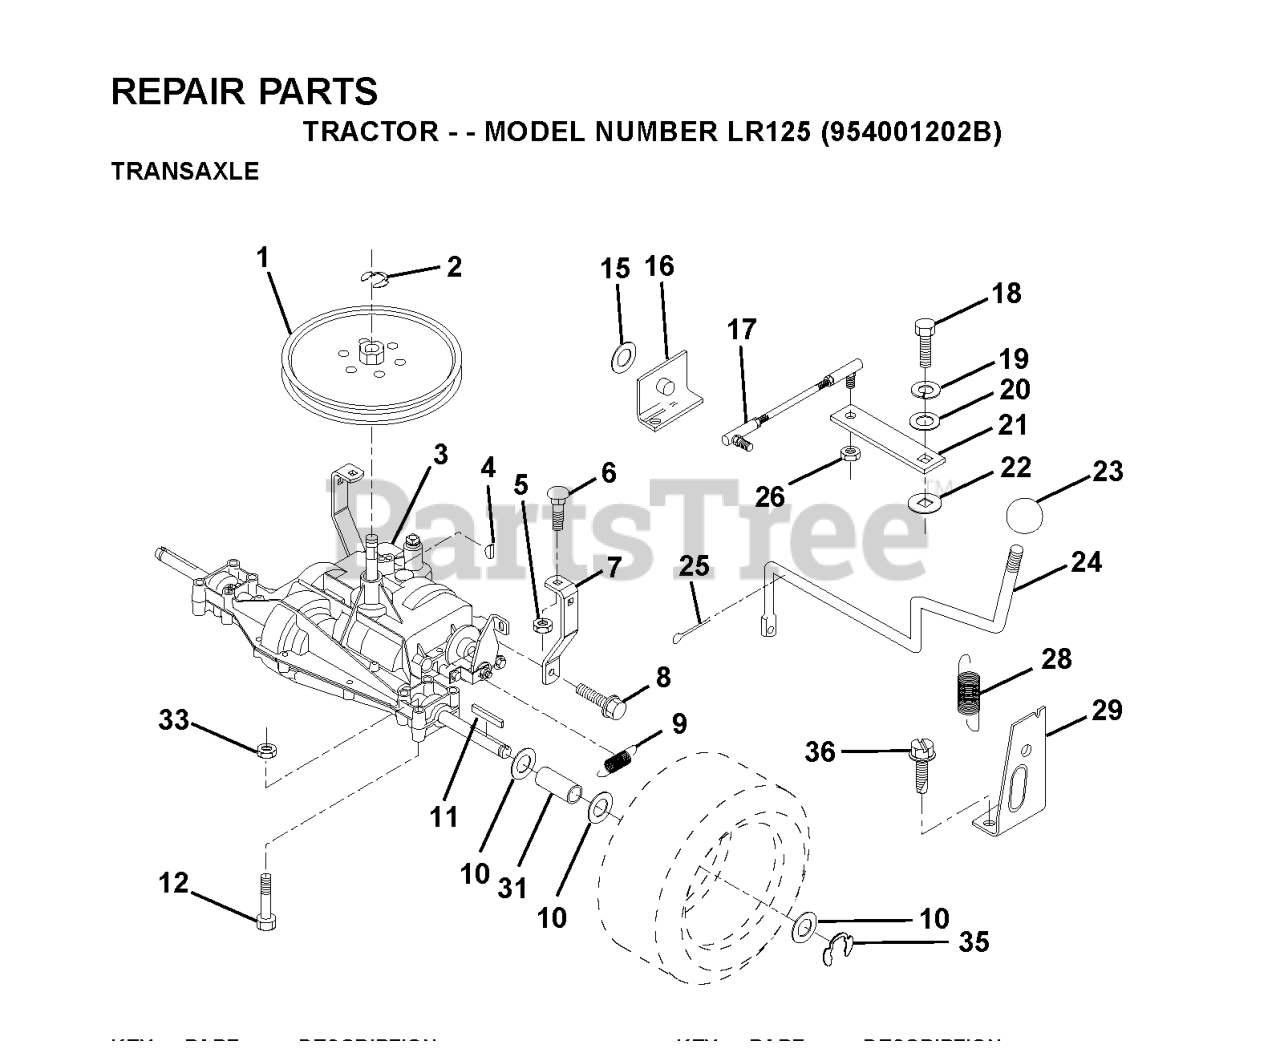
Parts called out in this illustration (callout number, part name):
2	RETAINING RING LT
3	TRANSAXLE
4	KEY STD (1373) DANA
5	LOCKNUT
6	RP BOLT 5/16-18 X3/4 ZN/YEL GR
7	STRAP,TORQUE
8	SCREW.THDROL.5/16-18X3/4.TTY
9	SPRING,BRAKE RETURN
11	SQUARE KEY
15	WASHER
16	SUPT, HDLE SHT LH
17	LINK,SHIFT
18	BOLT 1/4-28X3/4
19	LOCKWASHER
22	WASH-SHFT PLT LT
23	KNOB.DUCKHEAD.1/2
24	ROD, SHIFT
25	PIN COTTER
26	LOCKNUT
28	SPRING.EXTENSION
29	SUPPORT HANDLE SHAFT RH
36	SCREW
